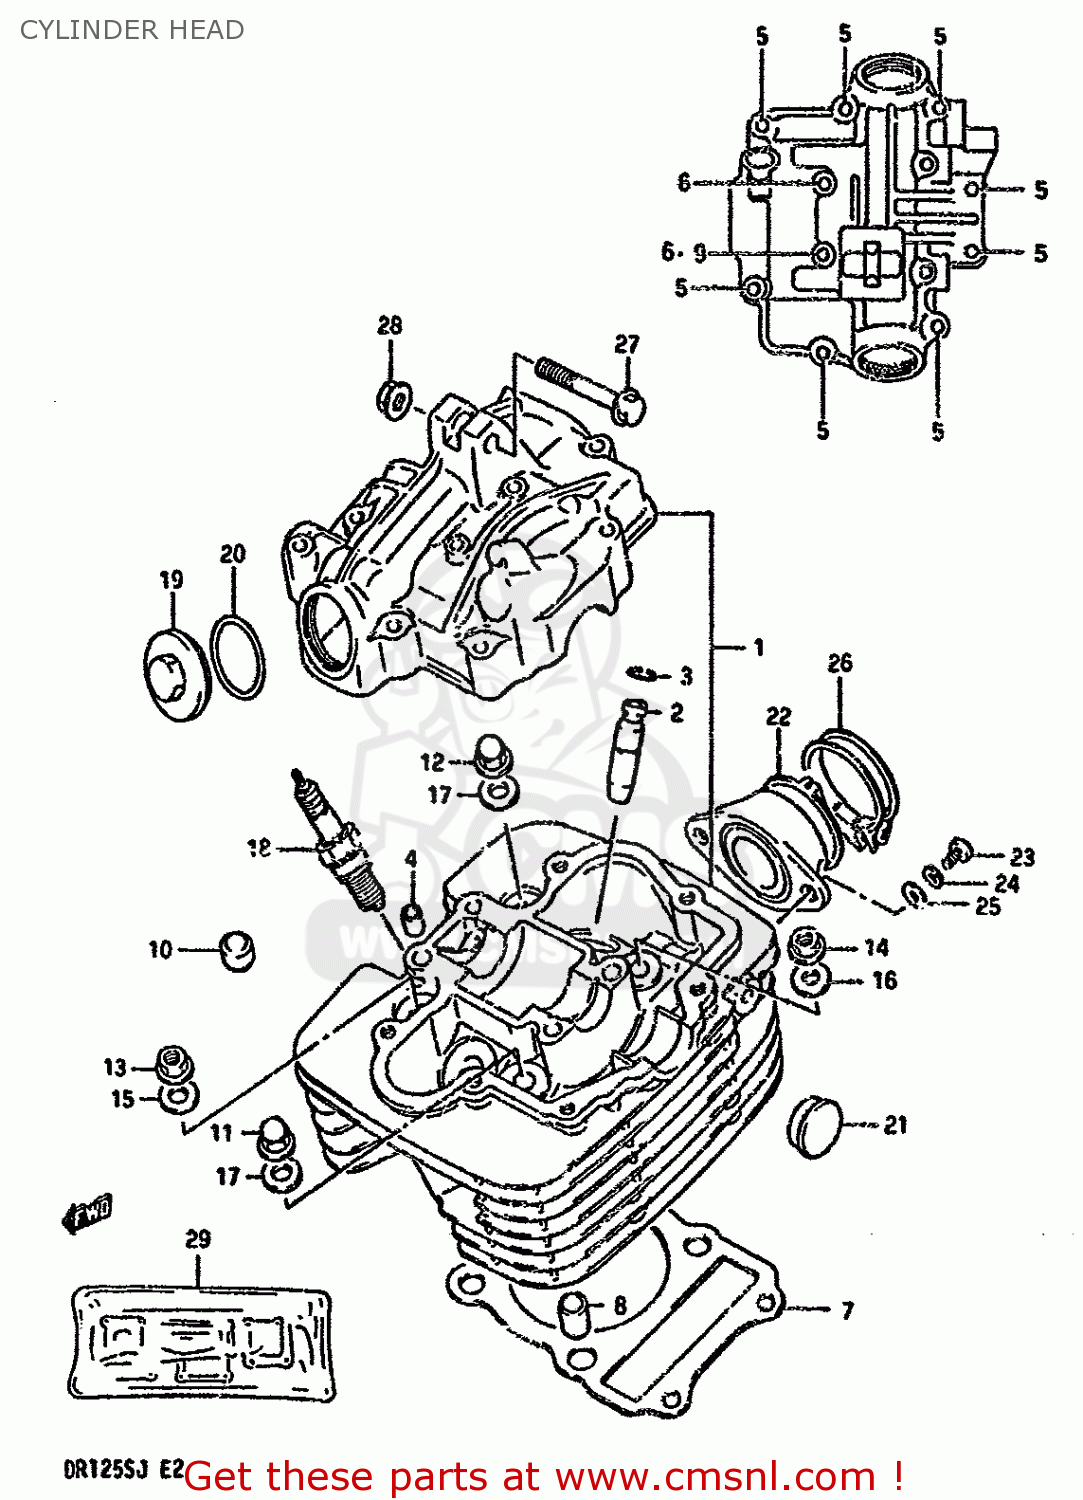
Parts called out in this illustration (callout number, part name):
1	HEAD ASSY,CYLINDER
2	GUIDE,VALVE
3	RING,SNAP
4	PIN(6.2X8X11)
5	BOLT 6X35
6	BOLT ,6X60
7	GASKET,CYLINDER HEAD (NAS)
8	PIN
9	GASKET(5.8X13X1.2) (NAS)
10	PAD,CYLINDER HEAD
11	NUT
12	NUT (8MM)
13	NUT 8MM
14	NUT
15	WASHER (8.5X19X2.3)
16	WASHER(8.5X19X2.3)
17	GASKET (NAS)
18	SPARK PLUG D8EA
19	CAP,INSPECTION
20	O RING(D:3,ID:29.5)
21	PLUG(OD:22.5)
22	PIPE,INTAKE
23	SCREW
24	WASHER,LOCK
25	WASHER
26	CLAMP
27	BOLT 8X50
28	NUT
29	GASKET SET
